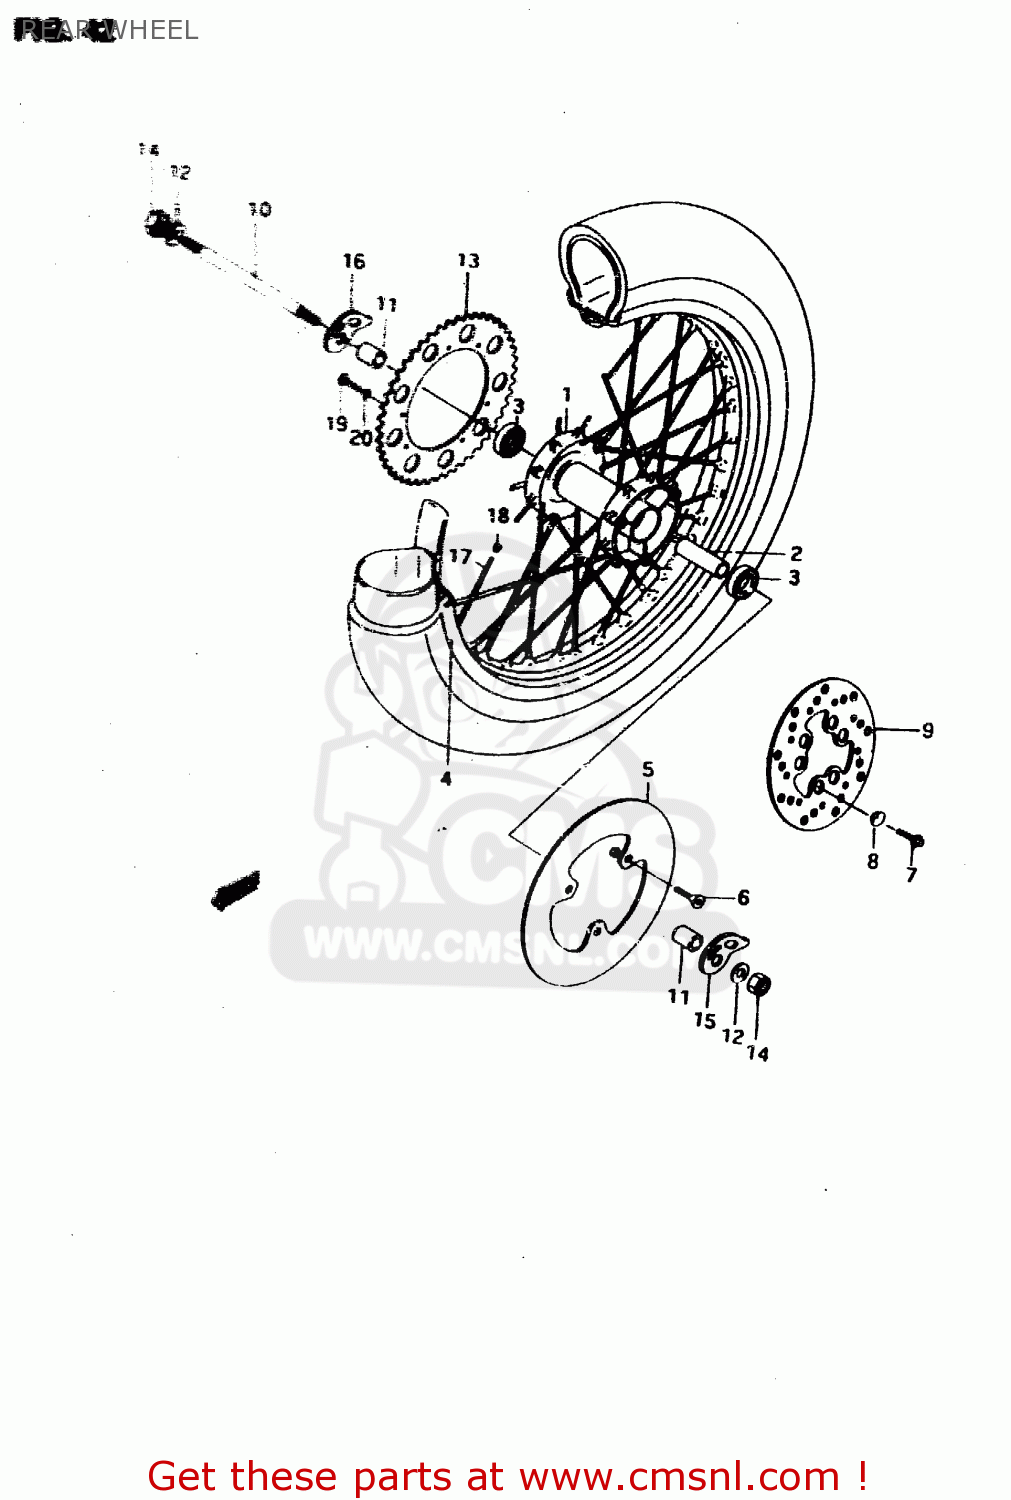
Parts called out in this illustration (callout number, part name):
1	HUB, REAR
2	SPACER
3	BEARING
4	RIM, WHEEL
5	DISC, REAR BRAKE
6	SCREW
7	BOLT
8	WASHER
9	DISC REAR BRAKE
10	AXLE, RR.
11	SPACER
12	WASHER
13	SPROCKET RR.
14	NUT
15	ADJUSTER, CHAIN
16	ADJUSTER, CHAIN RH
17	SPOKE
18	NIPPLE
19	BOLT
20	LOCK WASHER
